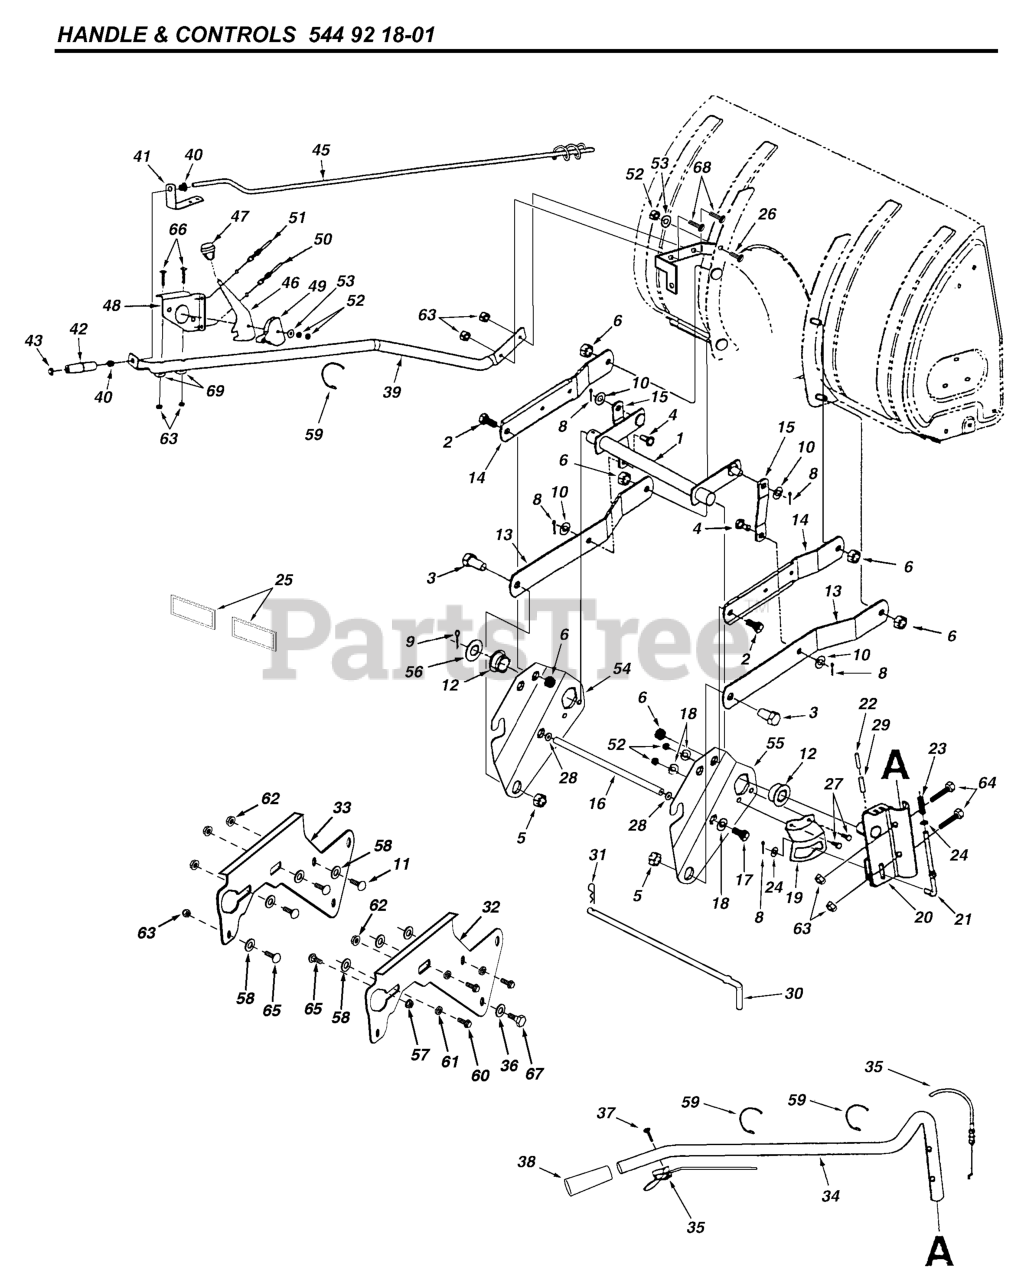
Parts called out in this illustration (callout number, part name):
2	BOLT 710-0865
3	BOLT 710-0367
4	PIN 711-0332
5	NUT 712-0261
11	BOLT 43350
13	LINK 783-0380
14	LINK 783-0381
15	LINK 24476
17	BOLT 47599
19	BRACKET 24820
20	BRACKET 63773
25	REFLECTOR 47788
26	RP BOLT 5/16-18 X3/4 ZN/YEL GR
27	BOLT.FIN.HEX.5/16-18X3/4
28	WASHER R19111116
32	PLATE 25678
33	PLATE 25679
36	WASHER
38	GRIP 46446
39	TUBE 47027
40	BUSHING 741-0475
47	KNOB 720-0232
49	CABLE GUIDE
53	WASHER BRB 8.4X17
54	PLATE 24285
55	PLATE 24284
58	WASHER R19172410
59	TIE WRAP 726-0178
60	BOLT 47631
61	Spring Washer
64	SCREW
66	BOLT 44215
67	BOLT 48106
68	BOLT 43682
